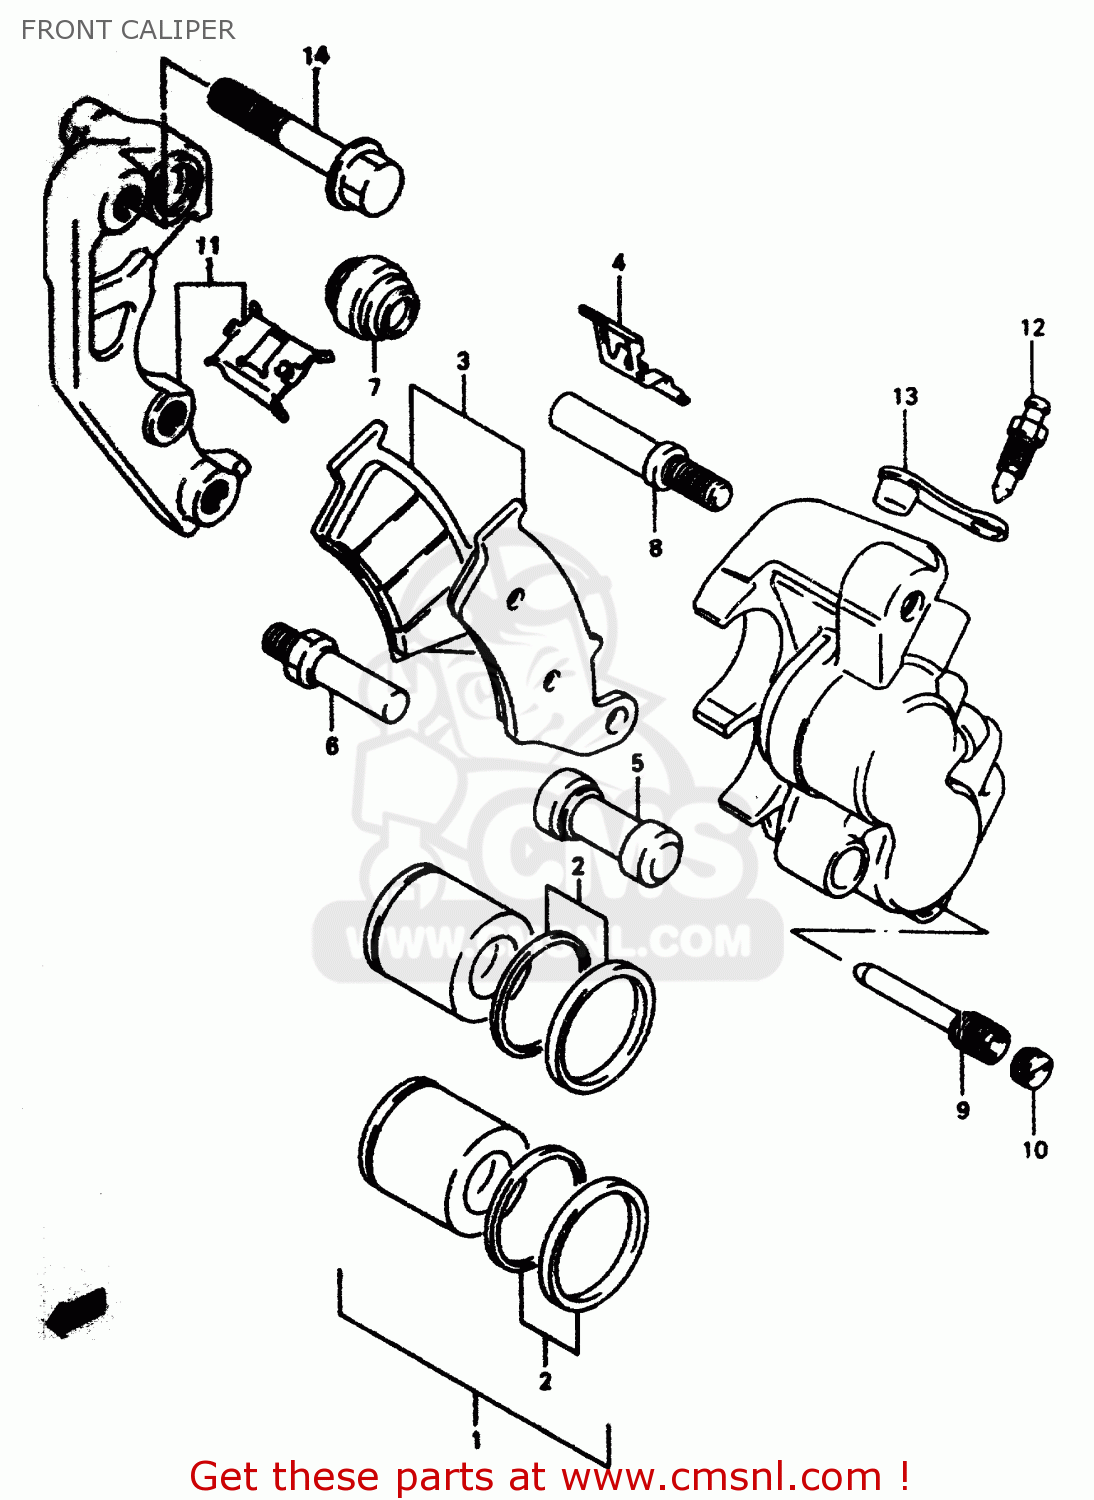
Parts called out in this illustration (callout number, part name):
1	PISTON SET
2	SEAL SET,PISTON
3	PAD SET (NAS)
4	SPRING,PAD
5	BOOT
6	PIN,BOLT
7	BOOT
8	PIN
9	PIN,HANGER
10	PLUG,PIN
11	BRACKET
12	BLEEDER
13	CAP,BLEEDER
14	BOLT(8X40)
